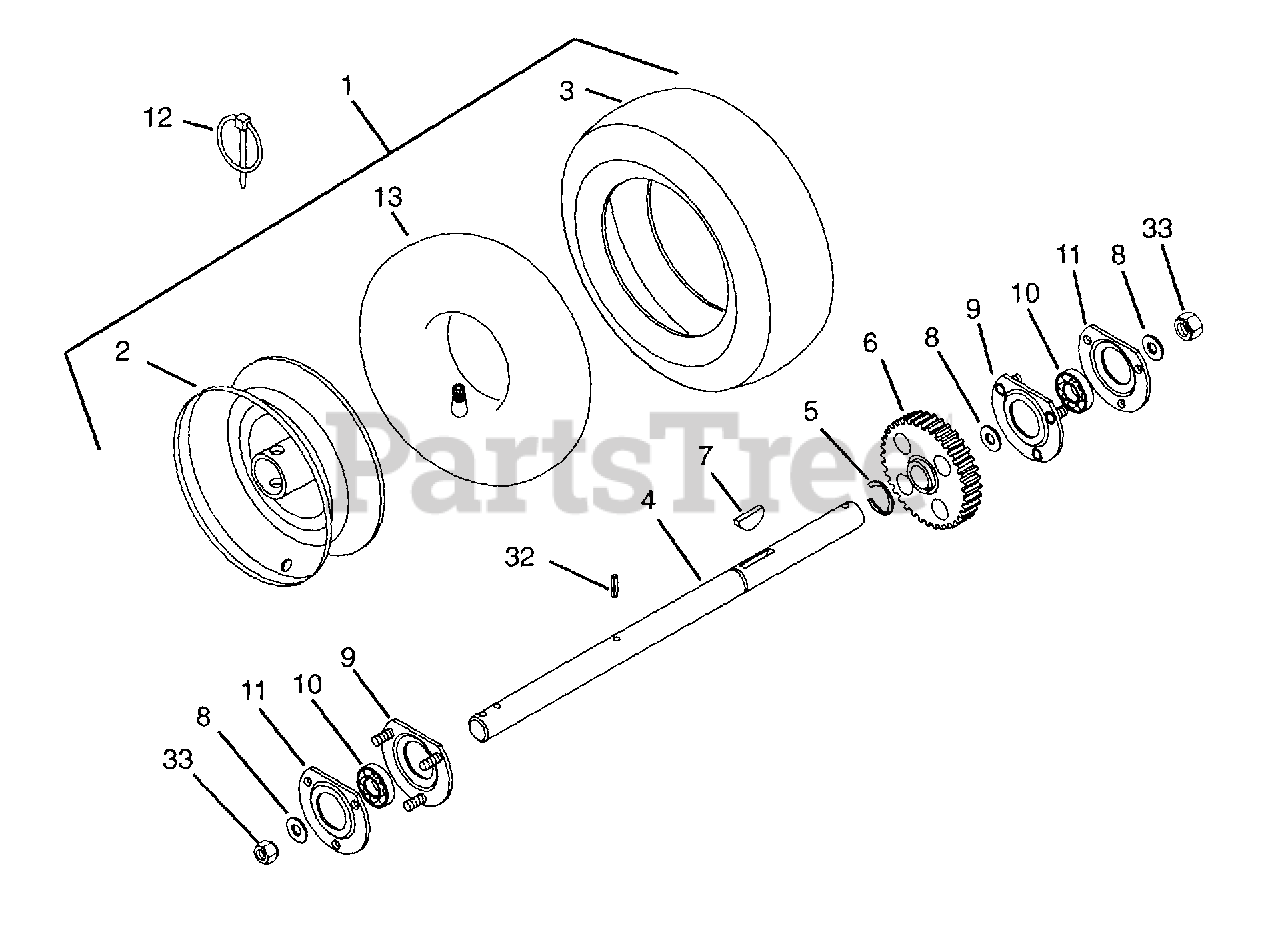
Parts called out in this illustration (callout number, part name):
1	TIRE/WHEEL ASSEMBLY 4.80X8
2	WHL 4.80-8
3	TIRE 4.80-8 NHS
4	SHAFT, AXLE
5	RG-RTNG-EXT. .875X.050
6	GEAR, SPUR
7	KEY-WDRF .25X.875X.375 SAE A
8	WSHR-FL-STL .880X1.250X.062YWZ
9	BEARING FLANGE
10	BRG-BALL .876 X 1.750 X .50
11	BEARING FLANGE
12	PIN-LOK .31X1.75
13	TUBE
32	PIN-ROLL .188X1.50
33	@NUT-LK-CTR .25-20 YWZC
